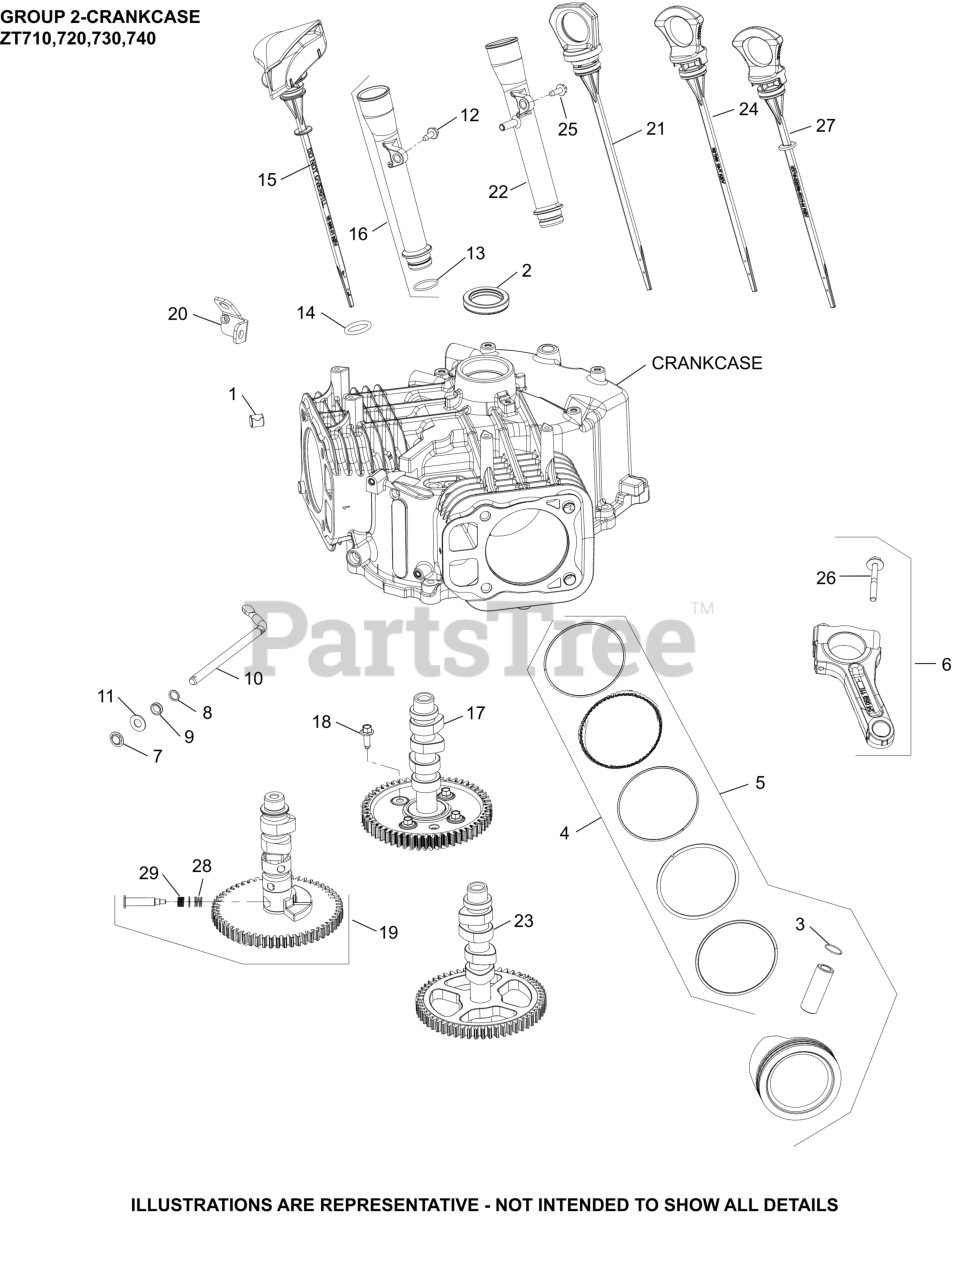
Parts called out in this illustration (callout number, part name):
1	PIN, LOCATING
2	SEAL, OIL (HELIX LIP)
3	RETAINER, PISTON PIN
5	KIT,PSTN/RNG STYLE B(STD)
6	ROD, ASSEMBLY CONNECTING
8	WASHER, FLAT 11/32"
9	SEAL, GOVERNOR CROSS SHAFT
10	KIT, CROSS SHAFT
11	WASHER, FLAT 9 MM
16	TUBE ASSEMBLY, OIL FILL
20	BRACKET, OIL FILL TUBE
23	CAMSHAFT ASSY
24	DIPSTICK, ASSY
25	SCREW, THREAD FORMING
